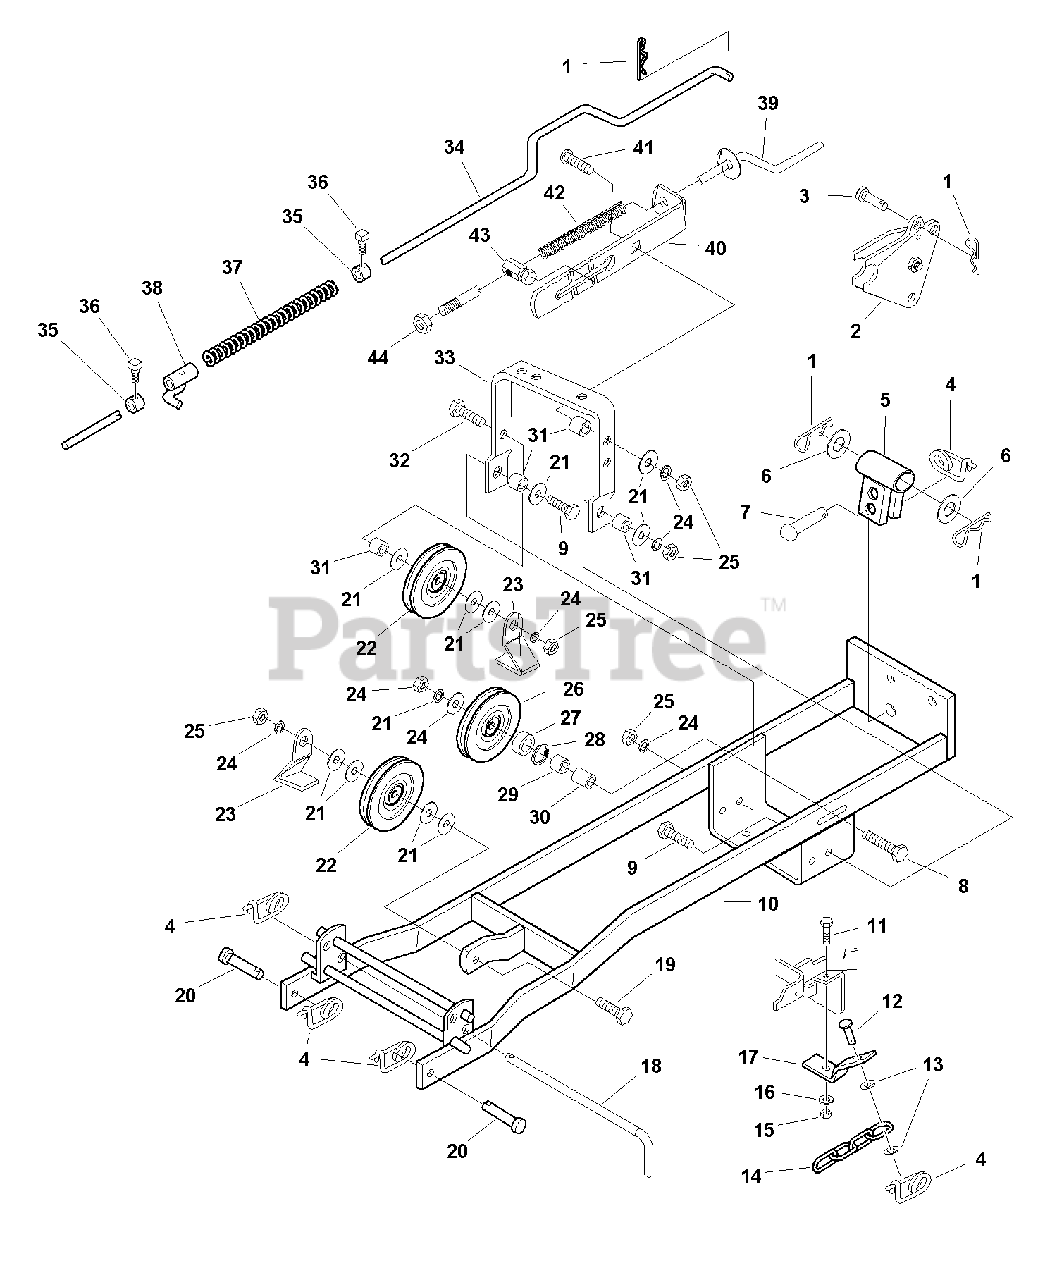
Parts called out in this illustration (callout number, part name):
2	EXTENSION ASSEMBLY
3	PIN, Round Head, Drilled
4	RETAINER,Pin
5	SUPPORT ASSEMBLY
6	WASHER
7	PIN, Round Head, Drilled
8	CAPSCREW, Whizlock, 3/8-16 x 2-3/4
9	CAPSCREW, Hex Head, 3/8-16 x 1-1/4
10	PUSH BAR ASSEMBLY
11	CAPSCREW, Hex Head, 5/16-18 x 1
12	PIN, Round Head, Drilled
13	WASHER, 5/16
14	CHAIN, Link
15	NUT, Hex, 5/16-18
16	LOCKWASHER, 5/16
17	BRACKET
19	CAPSCREW, Hex Head, 3/8-16 x 1-3/4
20	PIN, Round Head, Drilled, 3/8 x 1-1/2
21	WASHER, 3/8
23	STOP
24	LOCKWASHER, 3/8
25	NUT, Hex, 3/8-16
26	PULLEY & BEARING ASSEMBLY (Includes ref. nos. 28, 29)
28	RING, Retaining
32	CAPSCREW, Hex Head, 3/8-16 x 2-1/4
35	COLLAR
39	ROD, Adjustment
40	GUIDE
41	CARRIAGE BOLT, 3/8-16 x 1-1/4
44	LOCKNUT, 3/8-16
